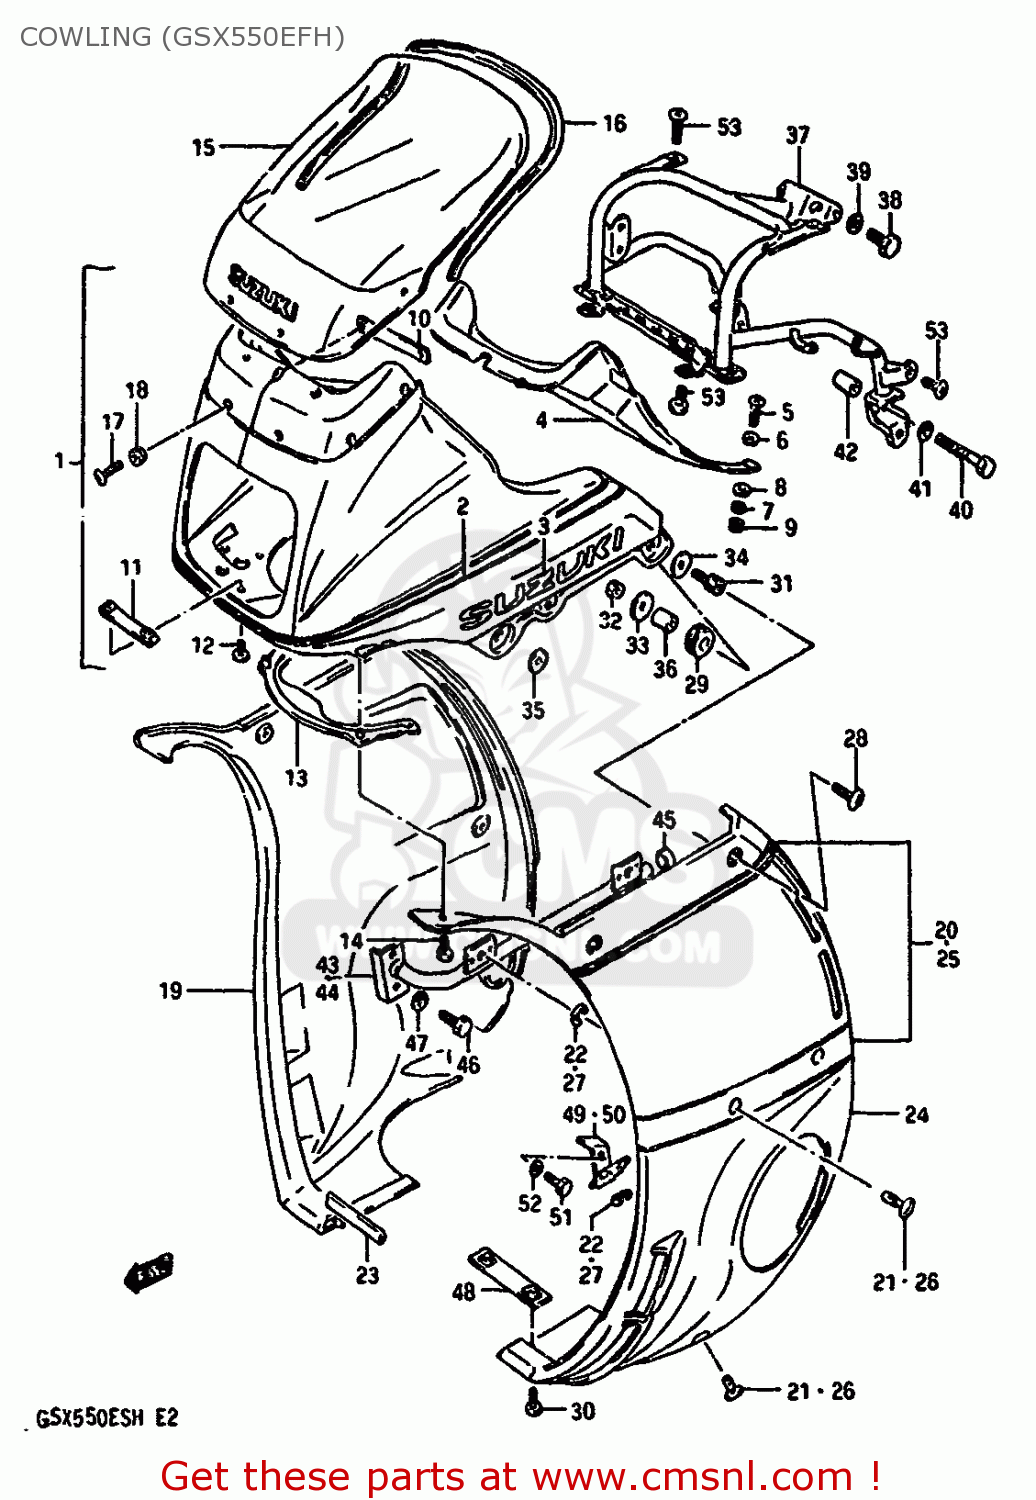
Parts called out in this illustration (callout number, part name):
1	COWLING ASSY (WHITE/RED)
2	TAPE SET
3	EMBLEM,FUEL TA
4	PANEL,COWLING,UPPER
5	SCREW
6	WASHER,5MM
7	WASHER,LOCK
8	WASHER,5MM
9	NUT ,5MM
10	BRACKET,COWLING,UPPER
11	BRACKET,COWLING,LOWER
12	SCREW
13	COVER,COWLING,LOWER
14	SCREW
15	WINDOW
16	MOULDING
17	SCREW
18	CUSHION
19	COVER,RH (WHITE/RED)
20	TAPE SET
21	FASTENER,COWL SIDE COVER
22	E-RING
23	MOLDING,LOWER
24	COVER,LH (WHITE/RED)
25	TAPE SET
26	FASTENER,COWL SIDE COVER
27	E-RING
28	SCREW,COWLING SIDE COVER
29	CUSHION
30	SCREW 6X12
31	BOSS,COWLING BODY,SIDE
32	NUT
33	WASHER (6.5X24X1.6)
34	WASHER, QUTER, REAR
35	WASHER(6.5X18X1)
36	SPACER (6.3X9.1X6.7)
37	BRACE,COWLING
38	BOLT
39	WASHER,LOCK,8.
40	BOLT
41	WASHER,LOCK,8.
42	SPACER (8.2X12.5X23.5)
43	BRACE,COWLING SIDE,RIGHT
44	BRACE,COWLING SIDE,LEFT
45	CUSHION
46	BOLT
47	WASHER,LOCK
48	BRACE,COWLING,LOWER,FRONT
49	BRACKET,COWLING SIDE,RIGHT
50	BRACKET,COWLING SIDE,LEFT
51	BOLT
52	WASHER,LOCK
53	SCREW 6X12
